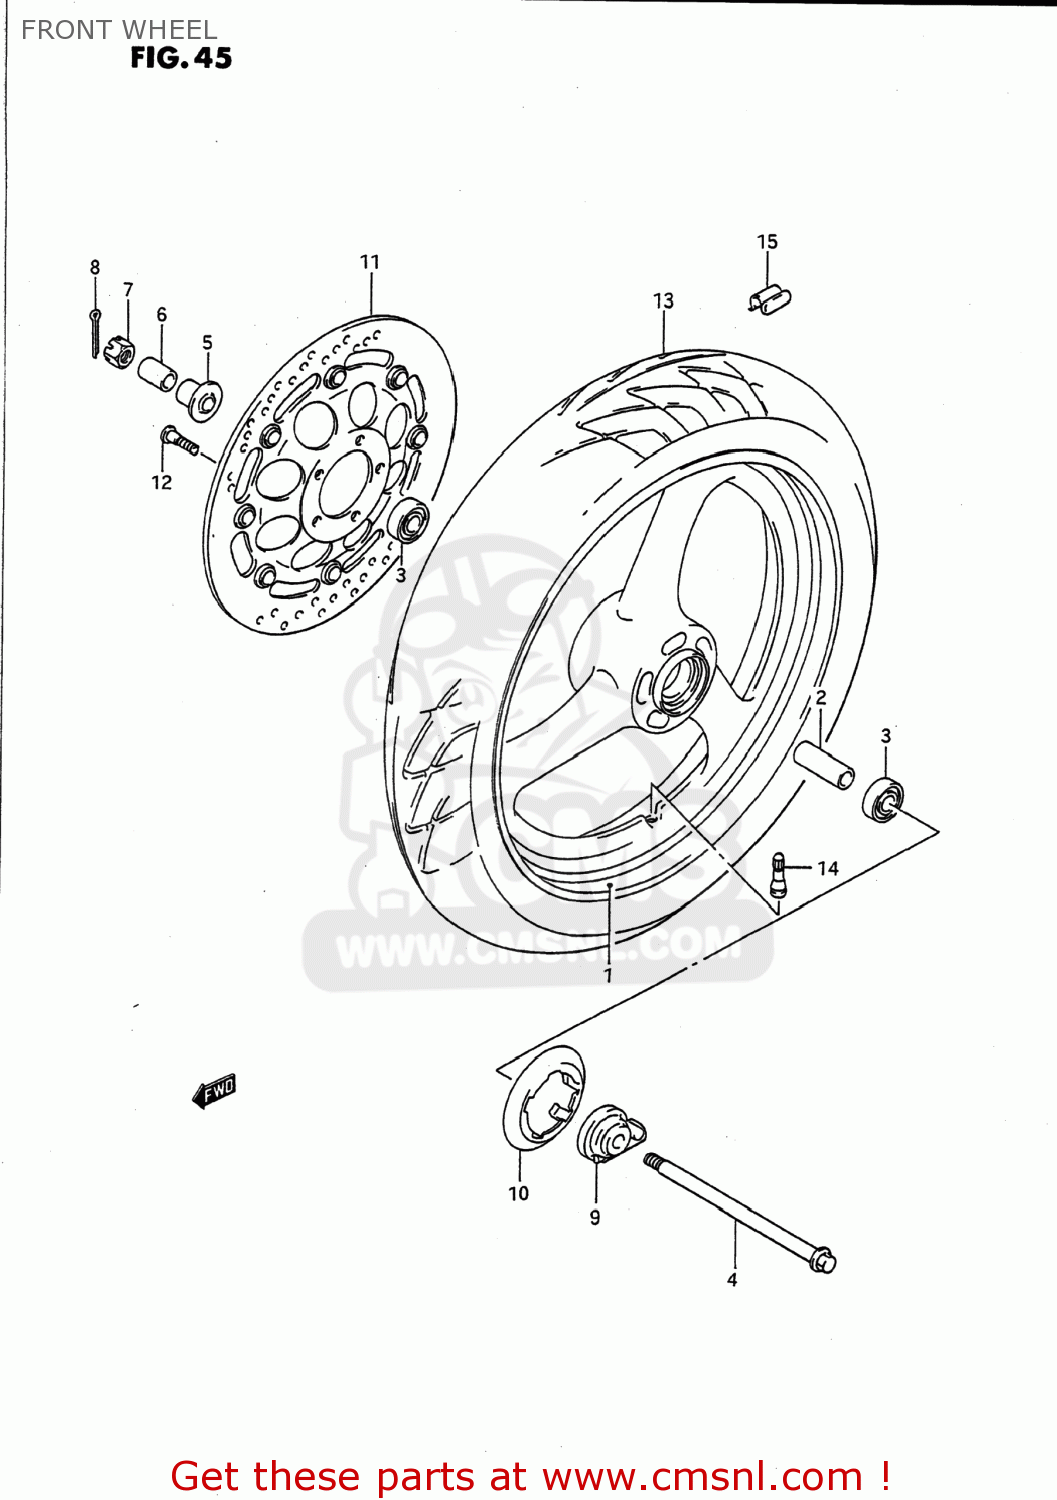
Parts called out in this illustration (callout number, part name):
1	WHEEL,FRONT (MT3.00X17)
2	SPACER(15.3X21.7X63)
3	BEARING
4	AXLE,FR
5	SPACER,FR AXLE
6	SPACER,FR AXLE,R
7	NUT
8	COTTER PIN
9	BOX ASSY,SPEEDOMETER GEAR
10	COVER,FR HUB,L
11	DISC,FR BRAKE,R
12	BOLT 8X33
13	TIRE,T/L(110/70-17 54H)
14	VALVE,TIRE
15	BALANCER,WHEEL
